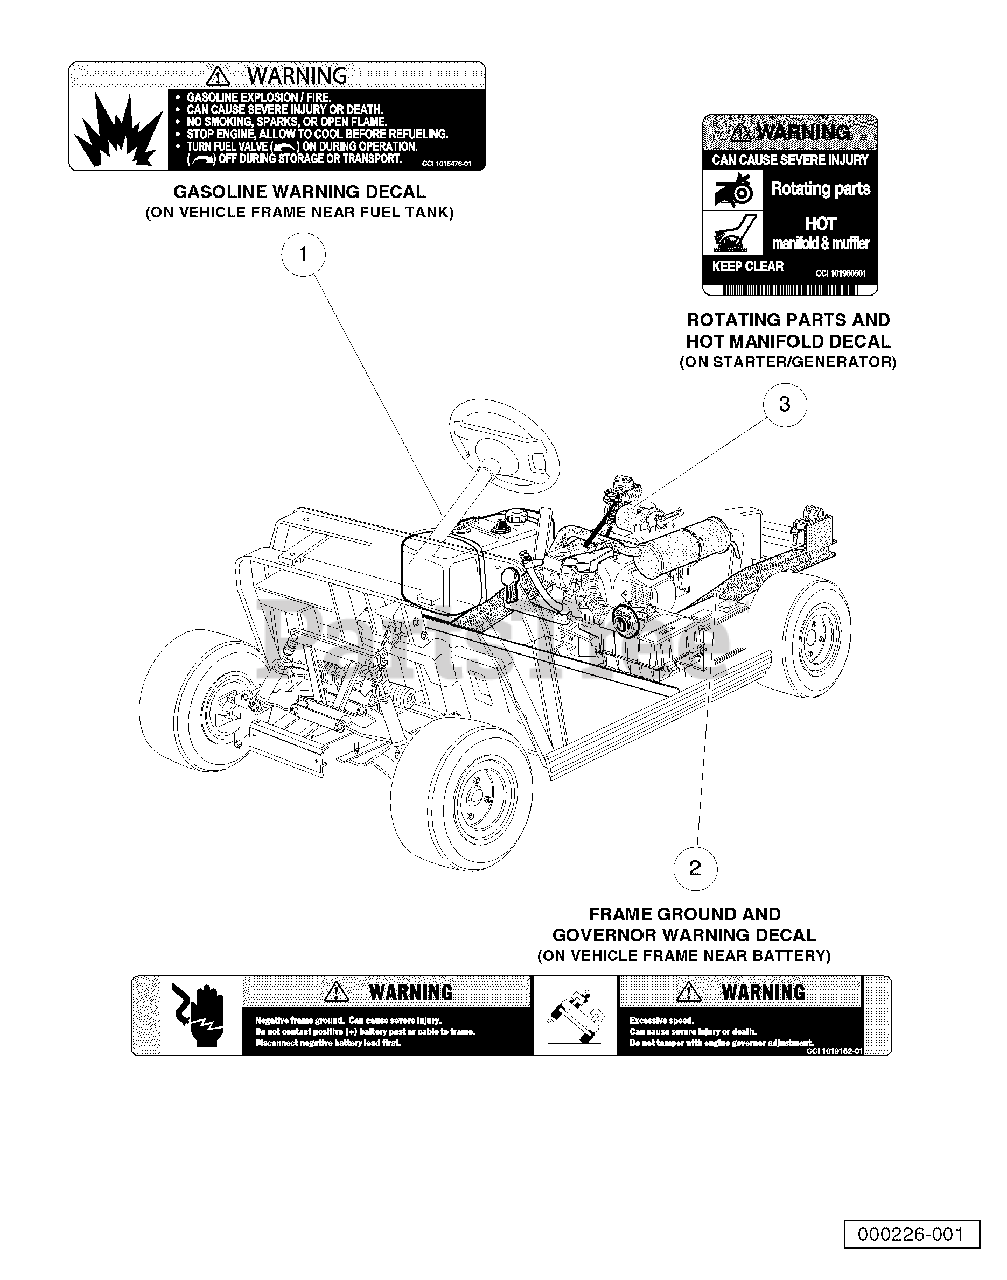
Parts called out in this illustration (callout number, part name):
1	Decal, Gasoline Explosion/Fire Warning
2	Decal, Frame Ground and Governor Warning
3	Decal, Rotating Parts/Hot Manifold
